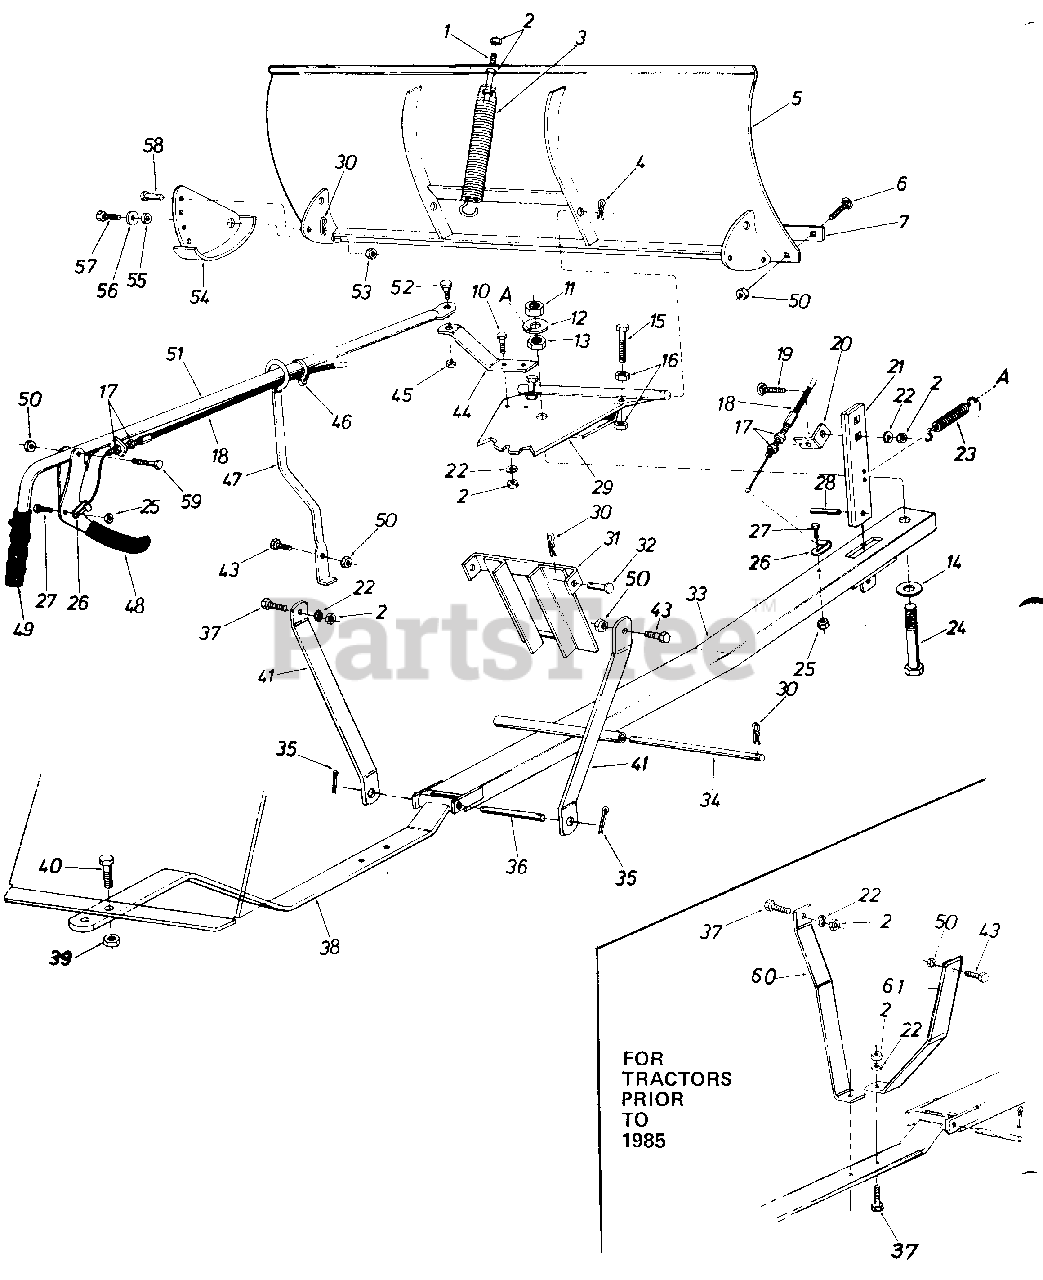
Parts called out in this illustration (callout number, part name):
1	Hex Scr. 3/8-16 x 4.50" Lg.*
2	Hex Nut 3/8-16 Thd.*
3	B1ade Adjustment Spring
4	Hair Pin Cotter 5/32" Dia.
5	48" BladeAss'y.
6	Carriage Bolt 5/16-18 x .75" Lg.*
7	Wear Plate 48"
10	Hex Scr. 3/8-16 x 1.00" Lg. *
11	Hex L.-Nut 3/4-10 Thd.
12	Fl.-Wash..810" I.D. x 2.00" O.D.
13	Hex Jam Nut 3/4-10 Thd. *
14	Fl.-Wash..810" I.D. x 2.00" O.D.
15	Hex Scr. 1/2-13 x 2.00" Lg.*
16	Hex Nut 1/2-13 Thd. *
17	Hex Jam Nut 5/16-24 Thd.*
18	Control Cable Ass'y.
19	Carriage Bolt 3/8-16 x 1.25" Lg.*
20	Cable Guide Bracket
21	Angle-Lock Bar
22	L.-Wash. 3/8" Scr.*
23	Angle Lock Spring
24	Hex Scr. 3/4-10 x 4.00" Lg.
25	Hex L.-Nut 1/4-20 Thd.
26	Clevis Lanyard Fitting
27	Hex Scr. 1/4-20 x .75" Lg.*
28	Spring Pin Spirol 1/4" Dia. x 1.00" Lg.
29	Pivot Plate Ass'y.
30	Hair Pin Cotter 3/32" Dia.
31	Guide Bracket Ass'y.
32	Clevis Pin 1/2" Dia. x 1.00" Lg.
33	Push Bar Ass'y.
34	Lift Shaft
35	Cotter Pin 5/32" Dia. x 1.00" Lg.*
36	Pivot Pin
37	Hex Scr. 3/8-16 x 1.25" Lg.*
38	Hanger Bracket Ass'y.
39	Hex L.-Nut 5/8-11 Thd.
40	Hex Scr. 5/8-11 x 1.50" Lg.*
41	Hanger Link
43	Hex 5/16-18 x 1.00" Lg. *
44	Blade Pivot Bracket
45	Hex L.-Nut 3/8-16 Thd.
46	Nylon Cable Tie
47	Tube Guide Ass'y.
48	Clutch Grip Ass'y.
49	Grip-3/4" Handle
50	Hex L-Nut 5/16-18 Thd.
51	Tube Handle Ass'y.
52	Shld. Scr.-Special 3/8-16 Thd.
53	Hex L.-Nut 3/8-16 Thd. .
54	Skid Assembly
55	Spacer
56	Fl.-Wash. .385" I.D. x 1.00" O.D.
57	Hex Scr. 3/8-16 x .75" Lg.*
58	Clevis Pin 5/16" Dia. x.75" Lg.
59	Hex Scr. 5/16-18 x 1.50" Lg.
60	Mounting Brkt.-L.H.
61	Mounting Brkt.-R.H.
